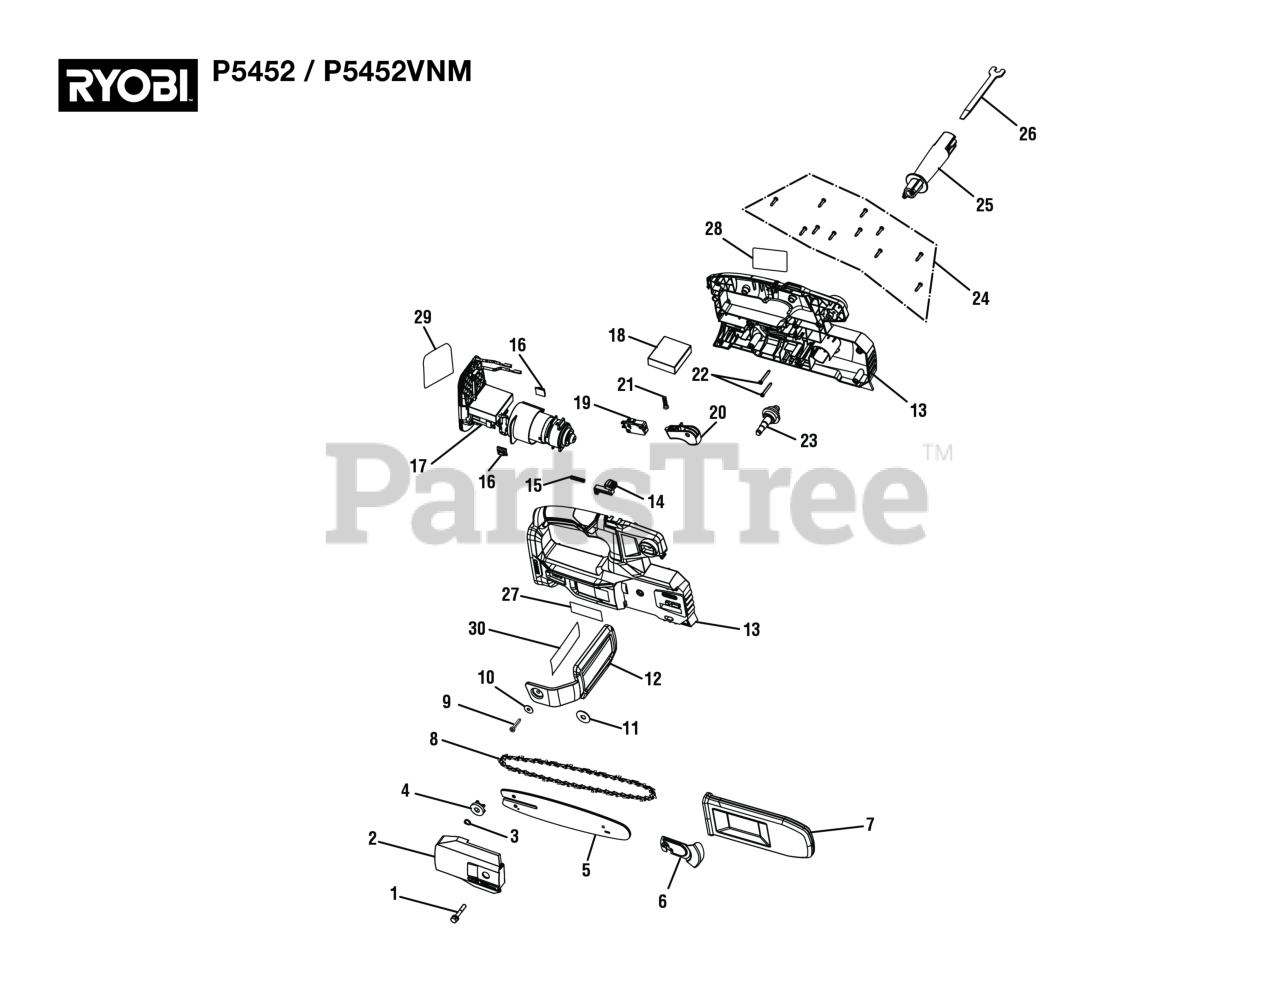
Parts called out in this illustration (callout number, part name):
1	Screw with Spring Washer (M6 x 35 mm)
2	Sprocket Cover Assembly
3	Retaining Ring
5	Guide Bar
6	Safety Tip Assembly
8	8 in. Saw Chain
9	Screw (T20 x 20 mm)
10	Flat Washer
11	Cover Plate (Internal "D" Washer)
12	Front Guard Assembly (Inc. Key No. 30)
13	Housing Assembly (Inc. Key Nos. 27-28)
15	Compression Spring (Trigger Lock)
16	Rubber Bumper
17	Motor, Gear Box, and Battery Foot Assembly (Inc. Key No. 29)
18	Balance Plate
19	On/Off Switch
21	Trigger Spring
22	Screw (M4-18 x 30 mm, T15 Torx Soc. Hd.)
23	Output Shaft Assembly
24	Screw (M4 x 16 mm, T20 Torx Socket Pan Hd.)
25	Front Handle Assembly
27	Logo Label
28	Warning Label
29	Data Label
30	Icon Warning Label
